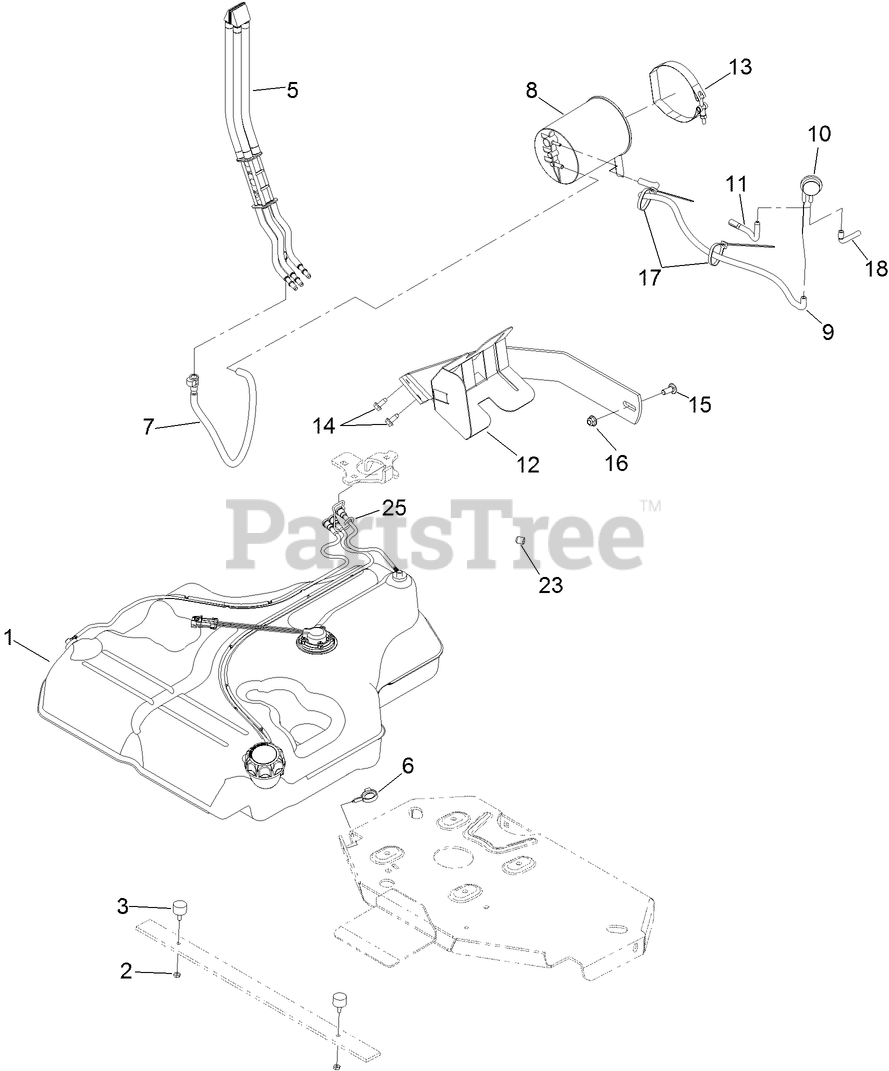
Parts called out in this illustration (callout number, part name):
1	FUEL TANK ASM
2	NUT-JAM
3	BUMPER-RUBBER (W/ STUD)
5	FUEL MANIFOLD VENT ASM
6	CLAMP-HOSE
7	VENT HOSE ASM
8	CANISTER-CARBON, 1200CC
9	HOSE-VENT, FORMED
10	VALVE-CONTROL, VACUUM
11	HOSE-VENT, FORMED
12	MOUNT-CANISTER
13	CLAMP-T-BOLT
14	SCREW-HWHTF
15	SCREW-CARR
16	NUT-HF, NI
17	TIE-PLASTIC
18	HOSE-VENT, FORMED
23	PLUG-PORT
25	RETAINER-LINE, VAPOR
